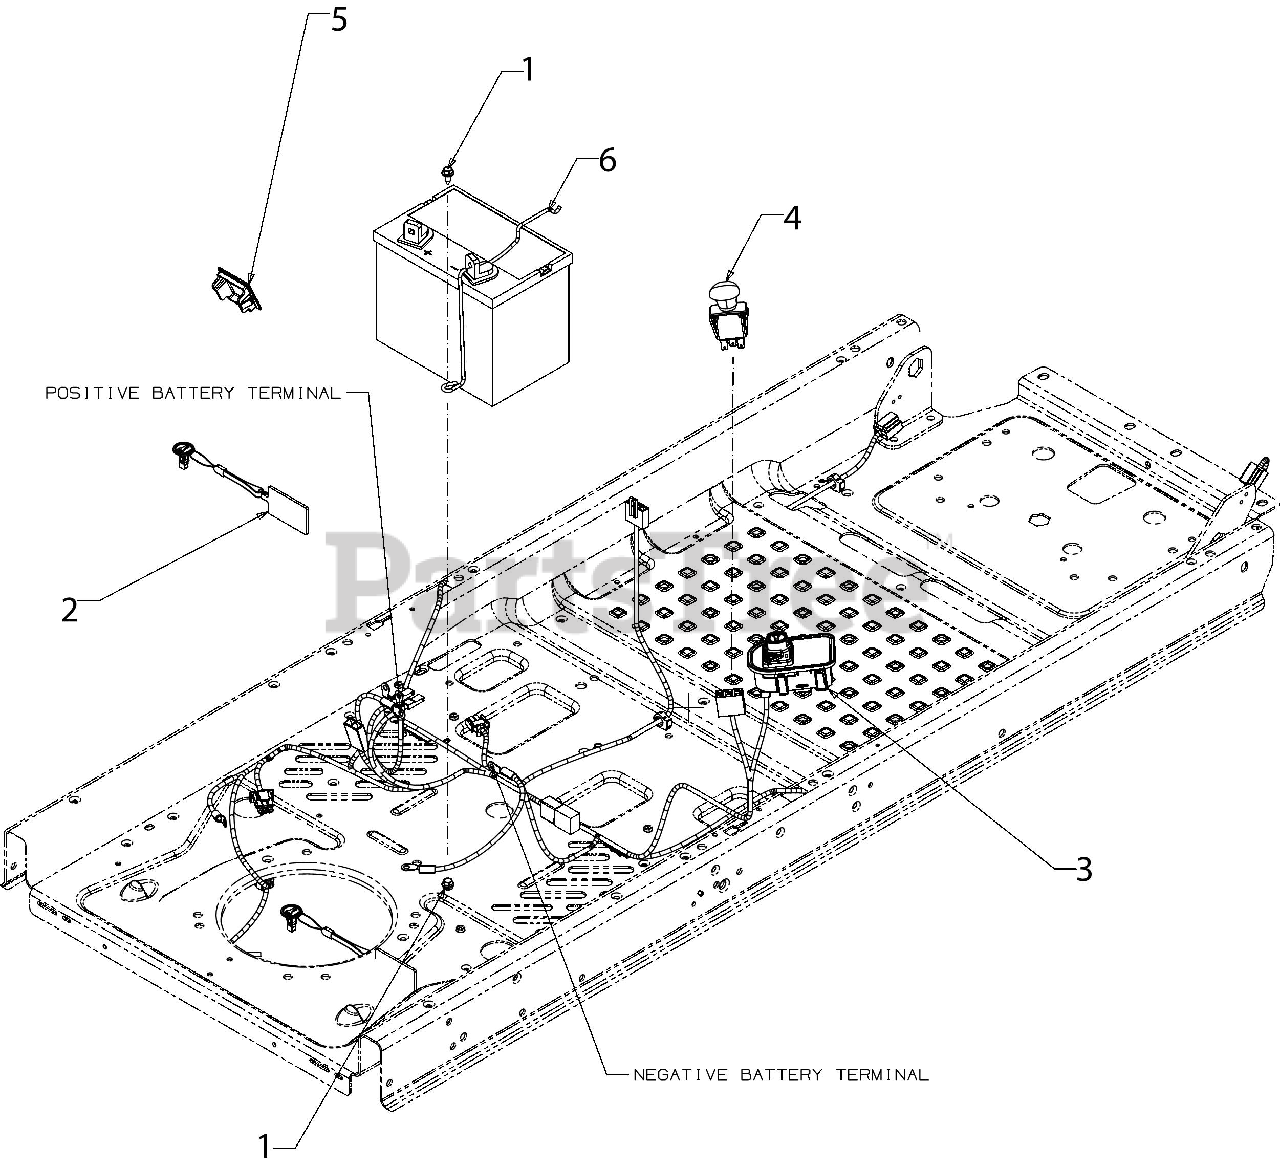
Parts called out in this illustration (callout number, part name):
1	SCREW 1/4-20X.625
2	PBS KEY
3	MODULE-PBS/HRMTR/SVC MNDR/BT
4	PTO SWITCH
5	DASH HOUR METER PLUG
6	BATTERY RETAINER
